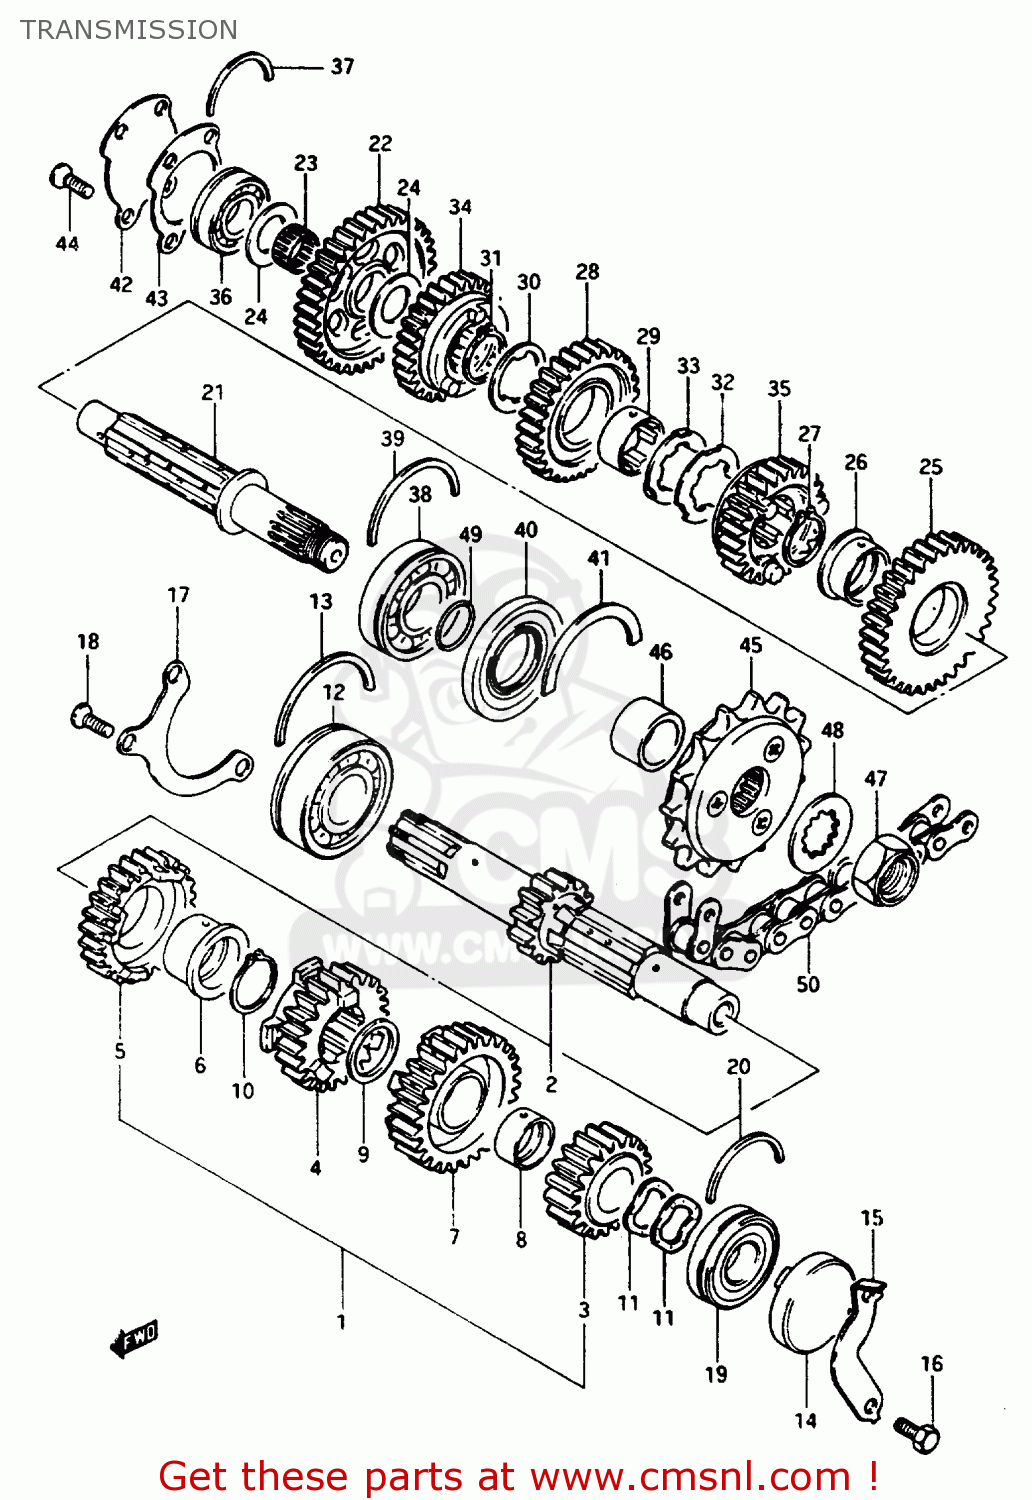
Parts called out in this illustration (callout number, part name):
1	SHAFT,COUNTER
2	SHAFT,COUNTER
3	GEAR,2ND DRIVE(NT:18)
4	GEAR,3RD DRIVE(NT:21)
5	GEAR,4TH DRIVE(NT:24)
6	BUSH(28X32X2)
7	GEAR,5TH DRIVE(NT:26)
8	BUSHING
9	WASHER
10	CIRCLIP
11	WASHER
12	BEARING(25X62X17)
13	C-RING
14	PLUG
15	RETAINER,CL PUSH ROD OIL SEAL
16	BOLT
17	RETAINER,CNTR SHAFT BEARING
18	SCREW
19	BEARING(20X47X14)
20	C RING
21	SHAFT,DRIVE
22	GEAR,FIRST DRIVEN (NT:35)
23	BEARING(20X24X10).8
24	WASHER
25	GEAR,2ND DRIVEN(NT:32)
26	BUSH(28X32X2)
27	CIRCLIP
28	GEAR,THIRD DRIVEN
29	BUSH,3RD DRIVEN GEAR
30	WASHER,LOCK
31	CIRCLIP
32	WASHER,LOCK
33	WASHER
34	GEAR,4TH DRIVEN(NT:27)
35	GEAR,5TH DRIVEN(NT:25)
36	BEARING
37	C RING
38	BEARING
39	C-RING
40	SEAL,OIL(32X62X5)
41	C RING
42	PLATE,DRIVE SHAFT
43	GASKET,DRIVESHAFT PLATE (MCA)
44	SCREW
45	SPROCKET,ENGINE
46	SPACER (25X32X21.6)
47	NUT
48	WASHER
49	O RING(D:1,ID:24.5)
50	CHAIN ASSEMBLY,DRIVE
